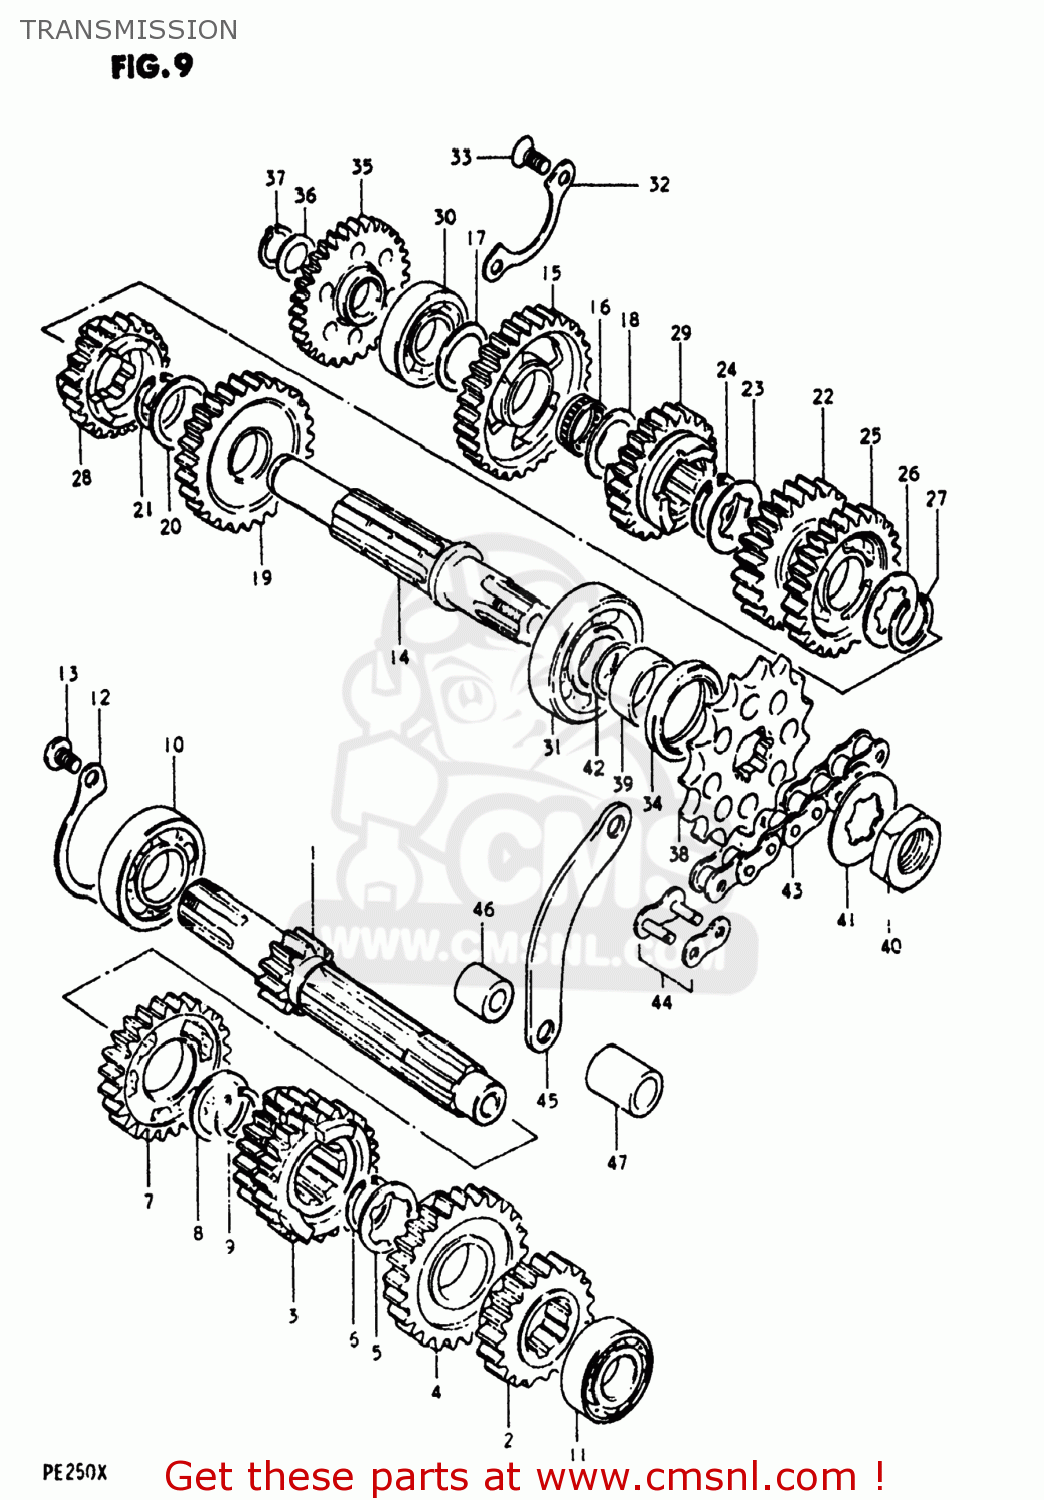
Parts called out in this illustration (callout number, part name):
1	SHAFT,COUNTER
2	GEAR,SECOND DRIVE
3	GEAR,THIRD/FOURTH DRIVE
4	GEAR,FIFTH DRIVE
5	WASHER,LOCK
6	CIRCLIP
7	GEAR,SIXTH DRIVE
8	SHIM(22X28X0.5)
9	CIRCLIP
10	BEARING
11	BEARING
12	PLATE,COUNTERSHAFT BEARING
13	SCREW 6X12
14	SHAFT,DRIVE
15	GEAR,FIRST DRIVEN
16	BEARING(17X21X9.8)
17	WASHER
18	WASHER,THRUST
19	GEAR,SECOND DRIVEN
20	SHIM(22X28X0.5)
21	CIRCLIP
22	GEAR,THIRD DRIVEN
23	WASHER,LOCK
24	CIRCLIP
25	GEAR,FOURTH DRIVEN
26	WASHER,LOCK
27	CIRCLIP
28	GEAR,FIFTH DRIVEN
29	GEAR,SIXTH DRIVEN
30	BEARING
31	BEARING
32	PLATE,DRIVESHAFT BEARING
33	SCREW
34	SEAL,OIL(32X42X6)
35	GEAR,KICK STARTER IDLE
36	CIRCLIP
37	WASHER
38	SPROCKET,ENGINE
39	SPACER(22X32X11.5)
40	NUT
41	WASHER,LOCK
42	O RING(D:1.7,ID:22)
43	CHAIN ASSEMBLY,DRIVE
44	JOINT ASSEMBLY,CHAIN
45	PLATE,FR CHAIN GUIDE
46	SPACER(8.6X16X24)
47	CUSHION
